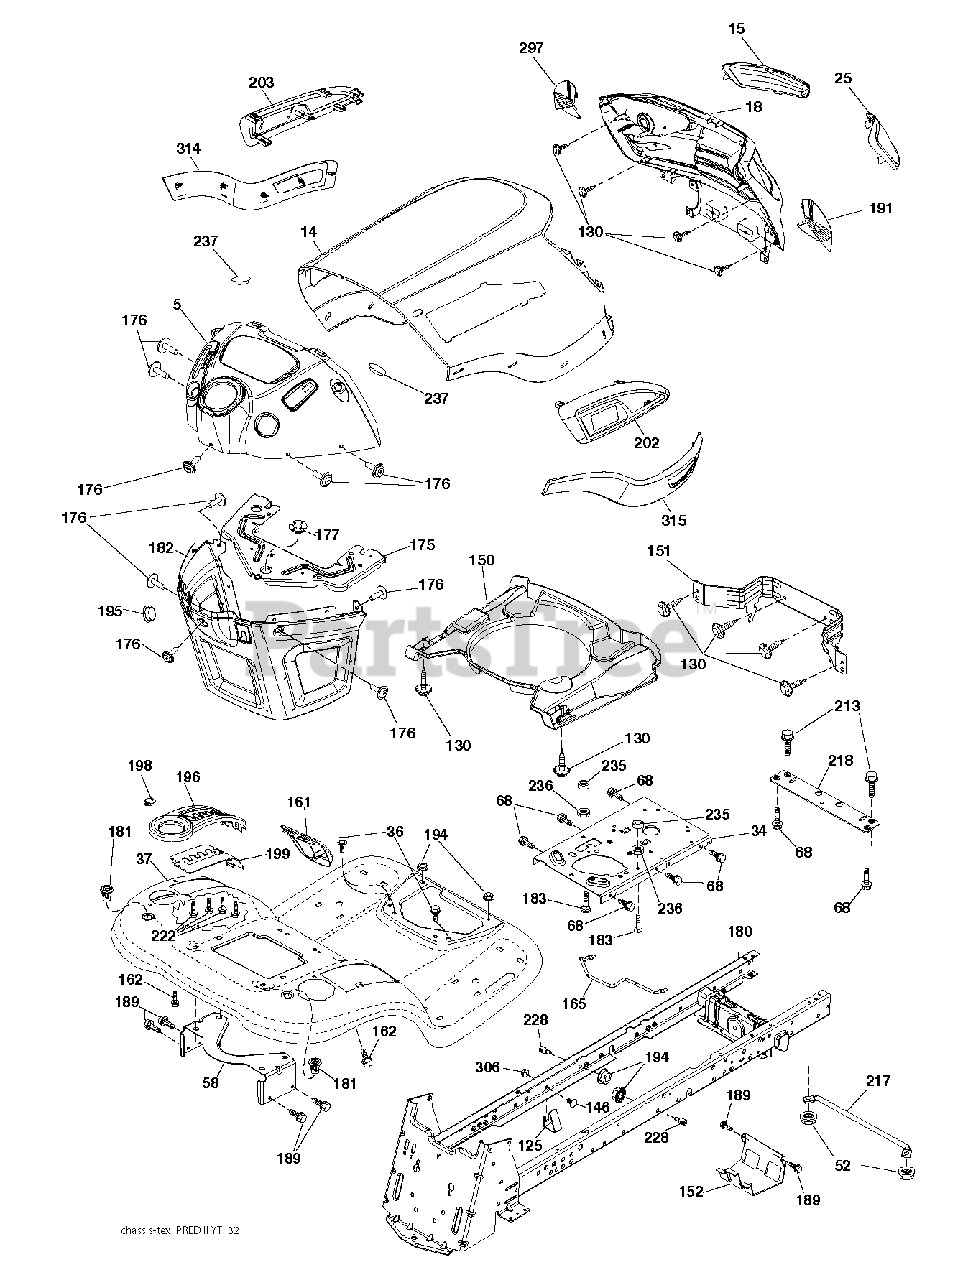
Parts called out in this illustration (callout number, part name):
36	SCREW 5/16"
52	LOCKNUT
58	BRKT.SUPPORT.FNDR/TANK
125	Fuel Line Clip
130	SCREW.#10 X 0.750.BOS THREAD
146	BOLT.RDHD.SHT.SQNK.3
150	PREDATOR.YT.GT.HOOD.A
152	SHIELD BROWNING
161	CONSOLE.FUEL.WINDOW.STGT.BLACK
162	SCREW.HI-LO.CONSOLE
165	SUPPORT.TANK.REAR.W/TE
175	PLATE.CROSSMEMBER.HUSQ
176	SCREW.#10-24X5/8.RN.QU
177	BUSHING STEERING
180	CHASSIS.GT.SLOPED.DRAWBAR.
181	BUSHING.MNT.FEND.CRGO.TEX.49
182	DASH LOWER.HUSQ.PRED NO CRUISE
183	BOLT.5/16-18X1-1/4 FULL THD
189	SCREW
194	NUT LOCK HEX FLANGE 5/16-18
195	PLUG.HOLE.DASH.LOWER.12V.BLK
198	INDICATOR.DECK.LIFT.RED
199	PLATE DECK LIFT
202	VENT.SIDE.RH.PRED2.GTYT.JONS
203	VENT.SIDE.LH.PRED2.GTYT.JONS
213	BOLT
217	ROD.PIVOT.HOOD
218	X-PIECE.HOOD.STOP.NON/
222	SCREW.1/4-20X5/8
228	STUD.FASTNER.W/ANTI-ROTATE
235	SPACER FENDER
236	NUT.CENTERLOCK.5/16-
237	PLUG.MOUNT.CARGO.BLK
306	NUT LOCK FLG 3/8-16 UNC
314	TRIM.SIDE.PRED2.LH.LGT54
315	TRIM.SIDE.PRED2.RH.LGT54
